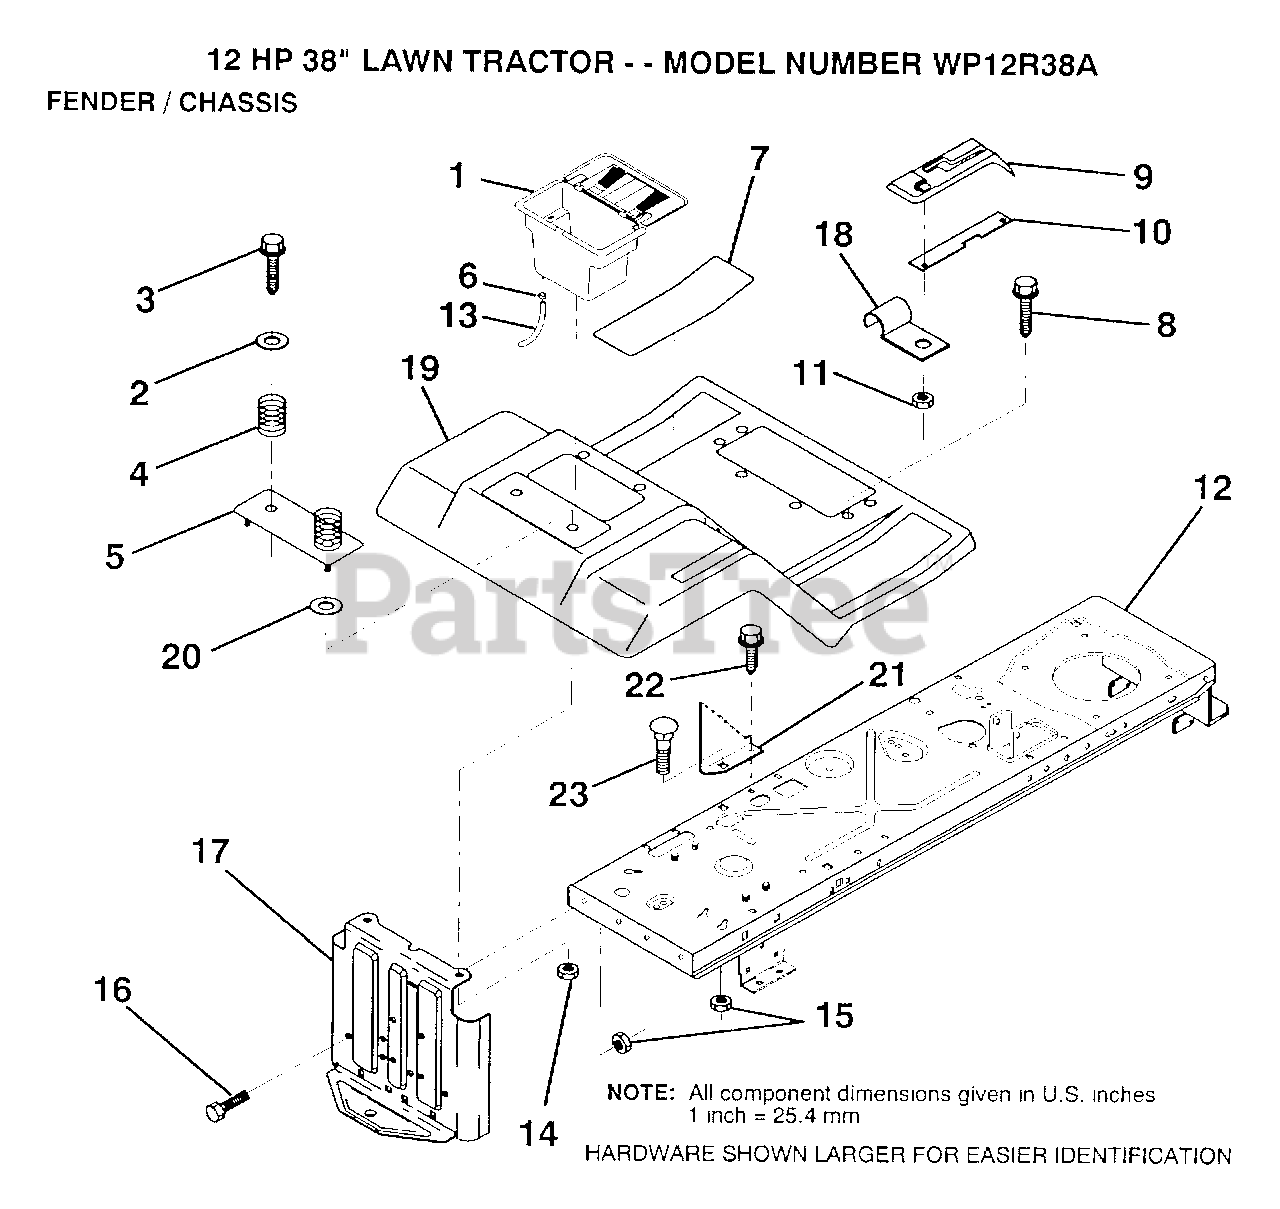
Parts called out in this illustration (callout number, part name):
2	WASHER
3	SCREW
4	SPRING COMPRESSIO
5	BTRY FENDER PLATE
6	HOSE CLAMP T
7	PAD FOOTREST
8	SCREW
10	"SHIFT LOCK, BAR"
11	NUT
14	NUT
16	BOLT
17	DRAWBAR
18	"CLIP,INSULATOR"
22	SCREW LT
